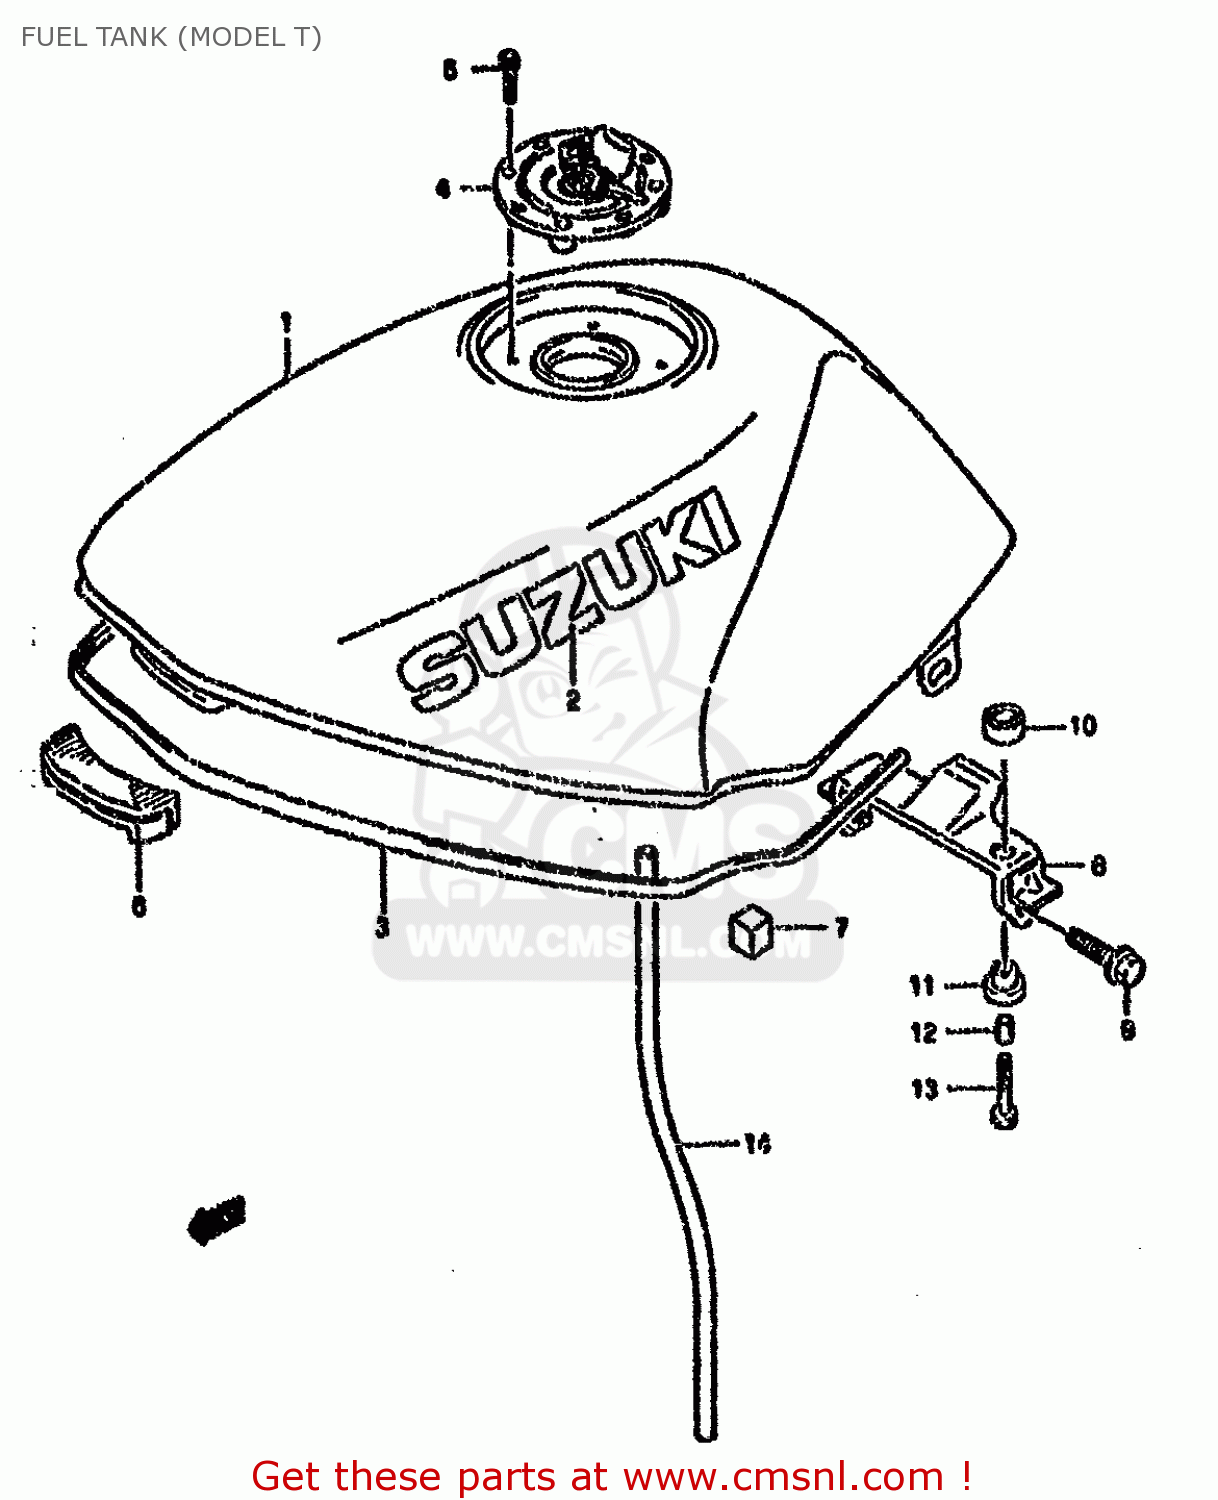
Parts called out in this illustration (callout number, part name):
1	TANK ASSEMBLY,FUEL
2	EMBLEM,FUEL TANK
3	MOLDING
4	CAP SET,FUEL TANK
5	BOLT(5X20)
6	CUSHION,FUEL TANK FR
7	CUSHION,FUEL TANK SIDE
8	BRACKET COMP,FUEL TANK
9	BOLT
10	CUSHION
11	CUSHION
12	SPACER
13	BOLT(6X30)
14	HOSE,WATER DRAIN
17	SPACER(6.1X9X18.2)
18	BOLT
19	HOSE,WATER DRAIN
